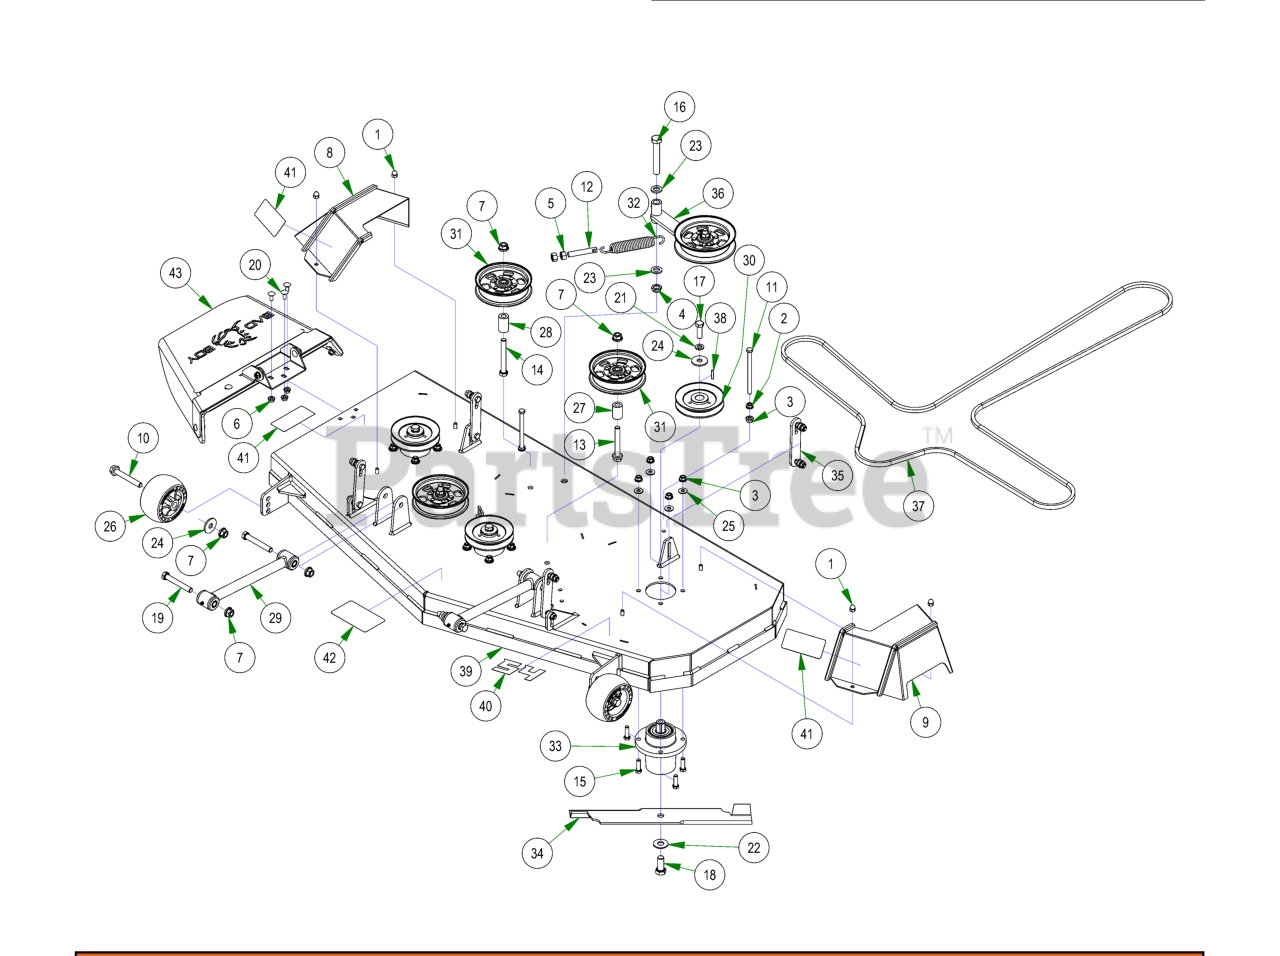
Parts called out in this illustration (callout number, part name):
1	5/16-18 ACORN NUT HIGH-CROWN ZC
2	3/8-16 HEX SERRATED FLANGE NUT HARD/ZINC
3	3/8-16 NYLON INSERT FLANGE LOCKNUT (GR.F) ZINC
4	5/8-11 NYLON INSERT JAM LOCKNUT ZINC
5	1/2-13 HEX NUT ZINC
6	5/16-18 NYLON INSERT FLANGE LOCKNUT ZINC
7	1/2-13 NYLON INSERT FLANGE LOCKNUT ZINC
8	2021 Maverick 54”/60” RH Pulley Cover
9	2021 Maverick 54”/60” LH Pulley Cover
10	1/2-13 X 90MM HEX FLANGE BOLT W/SHOULDER (GR.8) ZINC
11	3/8-16 X 5-1/4 HEX CAP SCREW (GR.5) ZINC
12	All Thread
13	1/2-13 X 3-1/2 HEX FLANGE BOLT (GR.8) ZINC
14	1/2-13 X 4 HEX CAP SCREW (GR.8) ZINC YELLOW
15	3/8-16 X 1-1/4 HEX CAP SCREW (GR.5) ZINC
16	5/8-11 X 4 HEX CAP SCREW (GR.8) ZINC YELLOW
17	1/2-20 X 1-1/2 HEX CAP SCREW (GR.5) ZINC
18	5/8-18 X 1-1/2 HEX CAP SCREW (GR.8) ZINC YELLOW
19	1/2-13 X 3-1/2 HEX CAP SCREW (GR.5) ZINC
20	5/16-18 x 3/4 Carriage Bolt
21	1/2 SPLIT LOCKWASHER (GR.8) ZINC/YELLOW
22	5/8 USS FLAT WASHER (1-3/4" OD) GR.8 ZINC YELLOW
23	.635 ID X 1.120 OD X .140 THICK FLAT WASHER NYLON
24	1/2 BELLEVILLE WASHER (1-5/8 OD X .140 THK) ZINC
25	5/16 USS FLAT WASHER (7/8 OD) ZINC
26	Deck Wheel
27	.502 ID X .750 OD X 1.500 Long Spacer
28	1 3/4" Pulley Spacer
29	Hybrid Turnbuckle/Deck Locator
30	54 MZ Spindle Pulley
31	5-3/4 Idler Pulley
32	Deck Idler Spring
33	Spindle Assembly-MZ
34	54" MZ Fusion Blade
35	Deck Hanger Assembly
36	2017 MZ/ZT Deck Idler Assembly
37	B155.75 Deck Belt
38	3/16 X 1 SQ MACHINERY KEY 1018 STL ZINC
39	2023 54" x 4" Deck
40	54" Deck Decal
41	Danger Decal-Spindle/Discharge
42	Deck Belt Route Decal
43	MZ Discharge Chute Assembly
